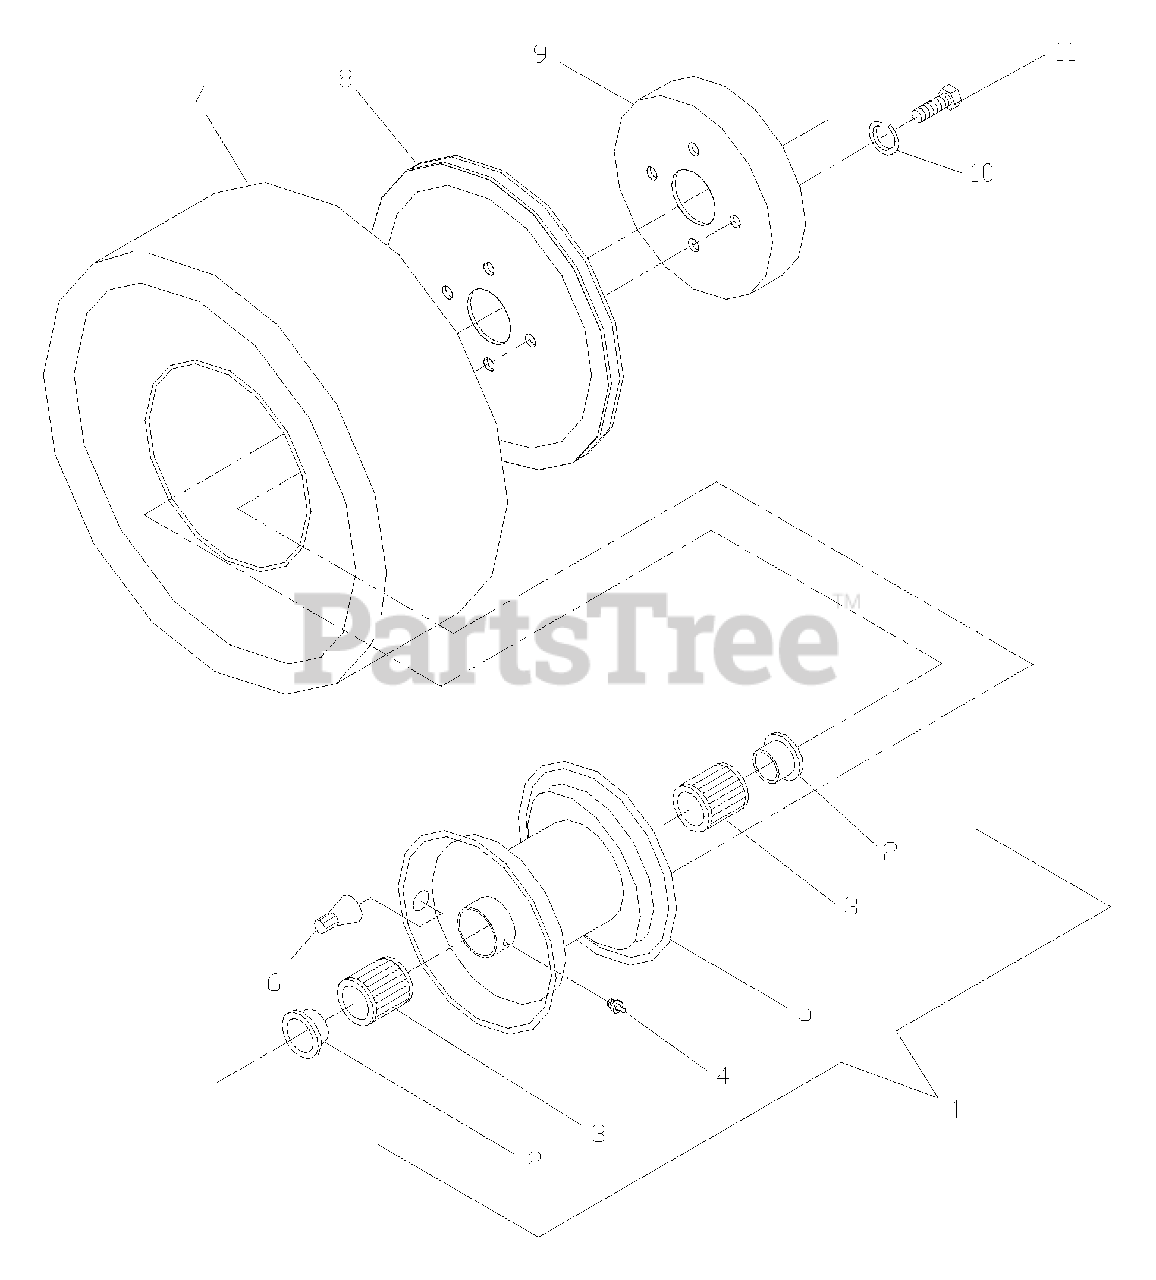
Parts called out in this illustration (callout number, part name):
1	WHEEL ASM.
3	ROLLER BEARING
4	ZERK 1/4-28 STRHT
5	RIM
8	TRACTION PULLEY
9	BRAKE DRUM
10	SLW 3/8 STD
11	HCS 3/8F X 3/4
